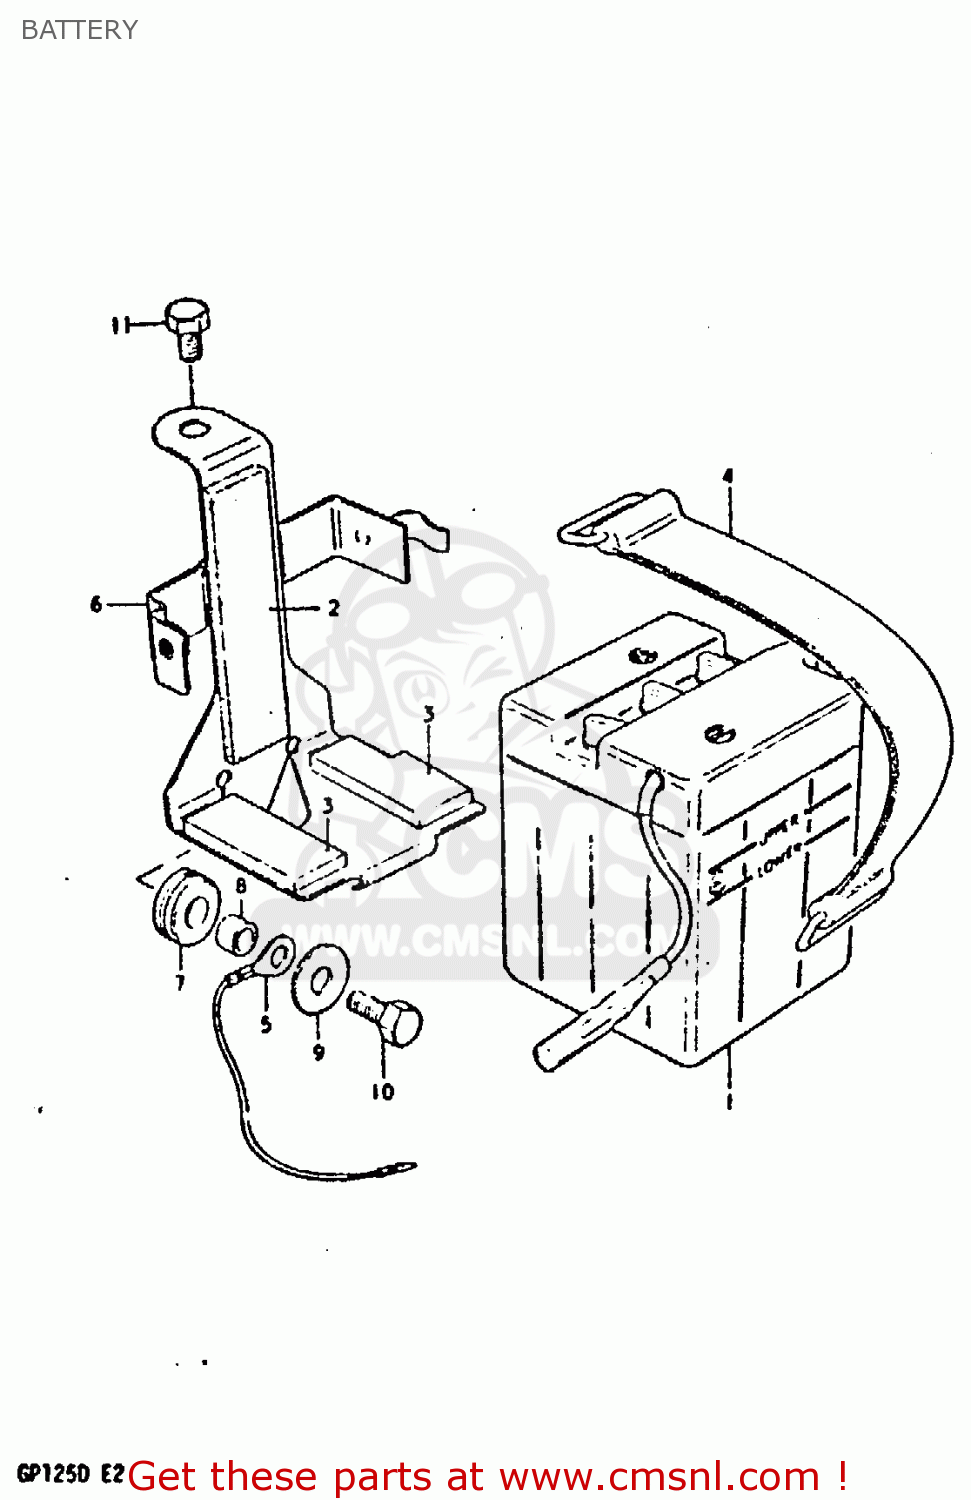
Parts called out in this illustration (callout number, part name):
1	BATTERY ASSY(6N4-2A4.2AH)
2	PROTECTOR,20X9
3	PROTECTOR,BATTERY
4	BAND
5	LEAD WIRE
6	HOLDER,BATTERY
7	CUSHION
8	SPACER(6.1X9X7.5)
9	WASHER
10	BOLT, UPPER
11	BOLT
